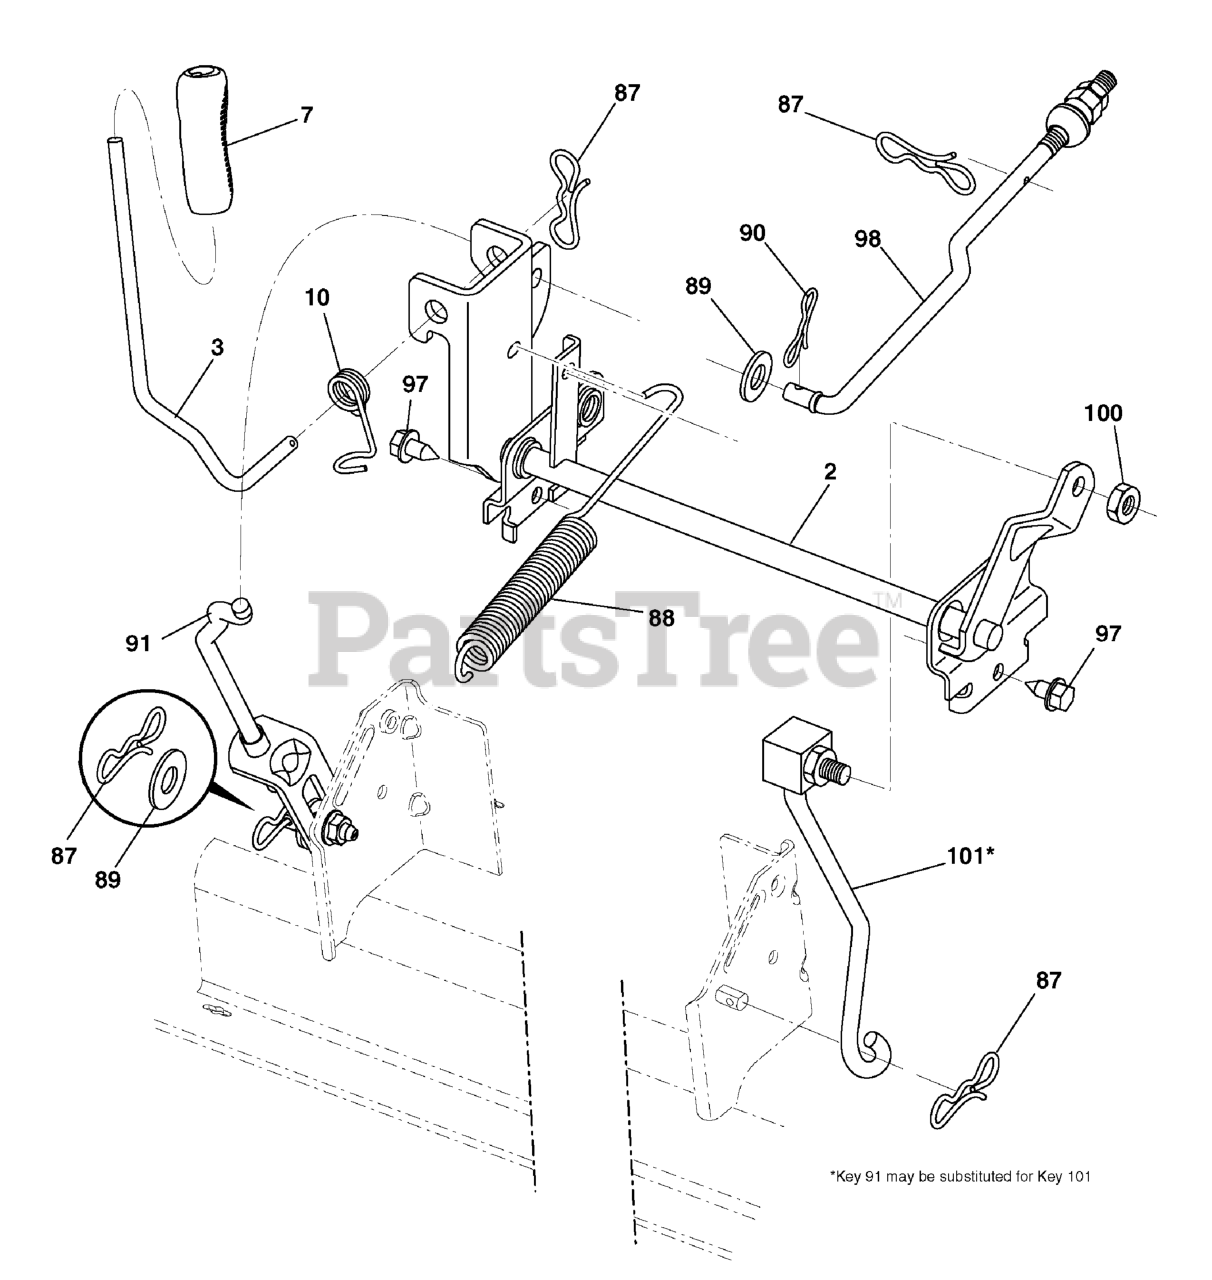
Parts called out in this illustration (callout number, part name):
2	Shaft Asm., Lift
3	Lever Asm., Lift RH
7	Grip, Lever
10	Spring Torsion
87	Pin Cotter 7/16 Bow Tie Lock
88	Spring Lift Assist
89	Washer Clear Zinc
90	Pin Cotter 5/16 Bow Tie Lock
91	Link Lift Susp Mower Rear
97	Screw 3/8-16 x .75 Smgml Tap/R.Z
98	Link Lift Susp. Front Mower
100	Nut Lock 3/8-16 unc
101	Link Asm Lift FXD
